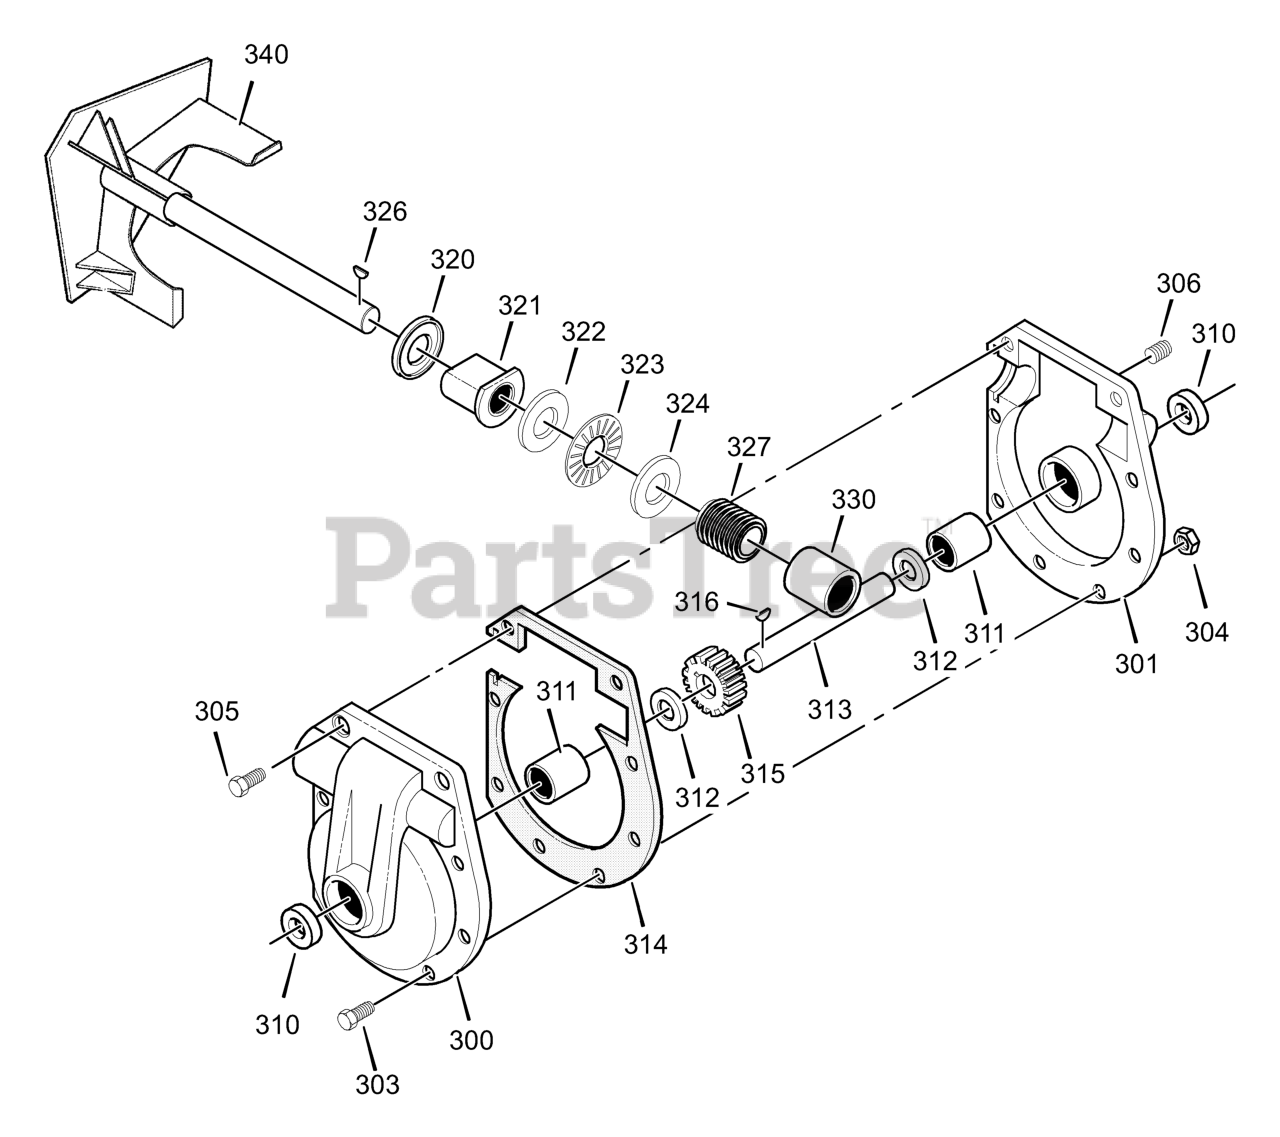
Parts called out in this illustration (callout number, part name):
300	CASE, GEAR, RH
301	CASE, GEAR, LH
303	SCREW, 5/16-24 x 1.00
304	NUT, 5/16-24
305	SCREW, 5/16-24 x 1.50
306	PLUG, PIPE 0.25-18
310	SEAL, OIL
311	BEARING, SLEEVE
312	WASHER, FLAT
313	SHAFT, AUGER OUTPUT
314	GASKET, GEAR BOX
315	WORM GEAR
316	KEY, WOODRUFF #91
320	RING, QUAD 0.924 ID
321	BEARING, FLANGE
322	WASHER, FLAT
323	BEARING, ROLLER
324	WASHER, FLAT
330	BEARING, SLEEVE
340	IMPELLER
